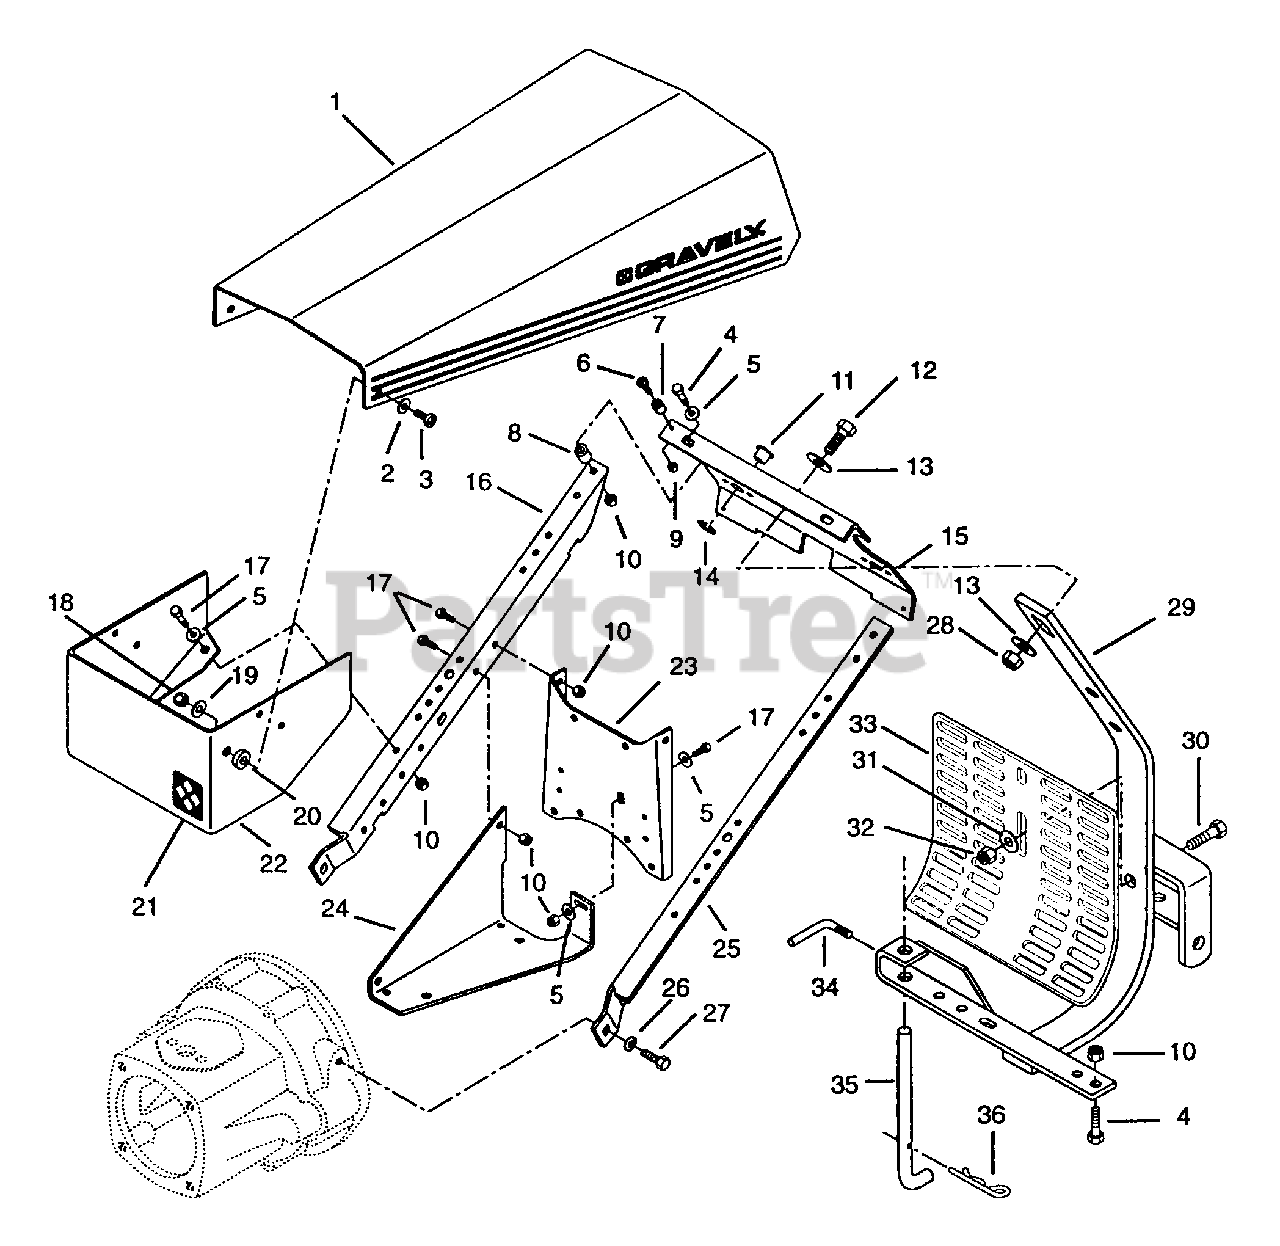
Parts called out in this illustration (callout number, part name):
1	Hood, Silk Screen 8 HP
2	Washer-Flat-Steel .281 x .620 x .065
3	Screw-Machine .250-20 x 1
4	Bolt-Hex .38-16 x 1.50 Grade 5
5	Washer-Flat-Steel .406 x .812 x .065
6	Screw-Machine 6-32 x .625
8	Bushing
9	Nut-Locking-Machine 6-32
10	Nut-Locking-Nylon .375-16 Grade 2
11	Bushing-Flange .515 x.750 x .745 x 1.00
12	Bolt-Hex .625-11 x 2.00
13	Washer-Flat-Steel .656 x 1.250 x .100
14	Ring-Retaining 1.000 x .748
15	Plate, Silk Screen, Man
16	Support, Handle Bar Right Hand
17	Bolt-Hex .380-16 x .875
18	Nut-Locking-Nylon .250-20 Grade 2
19	Washer-Flat-Steel .313 x .875 x .065
20	Bushing, Flange 280 x .750 x .318
21	Decal, Comm. Front
22	Support Hood
23	Bracket
24	Tray, Battery
25	Support, Handle Bar Left Hand
26	Washer-Lock .50 Reg.
27	Bolt-Hex.50-13 x 1 Grade 5
28	Nut-Locking-Nylon .625-11 Grade 2
29	Weldment, Hitch 8 HP
30	Bolt-Hex.50-13 x 1.50 Grade 5
31	Washer-Flat-Steel .531 x 1.250 x .100
32	Nut-Locking-Nylon .50-13 Grade 5
33	Guard, Engine
34	Handle, Adjusting
35	Stand, Kick
36	Pin-Hair-Internal .15 x 2.937
